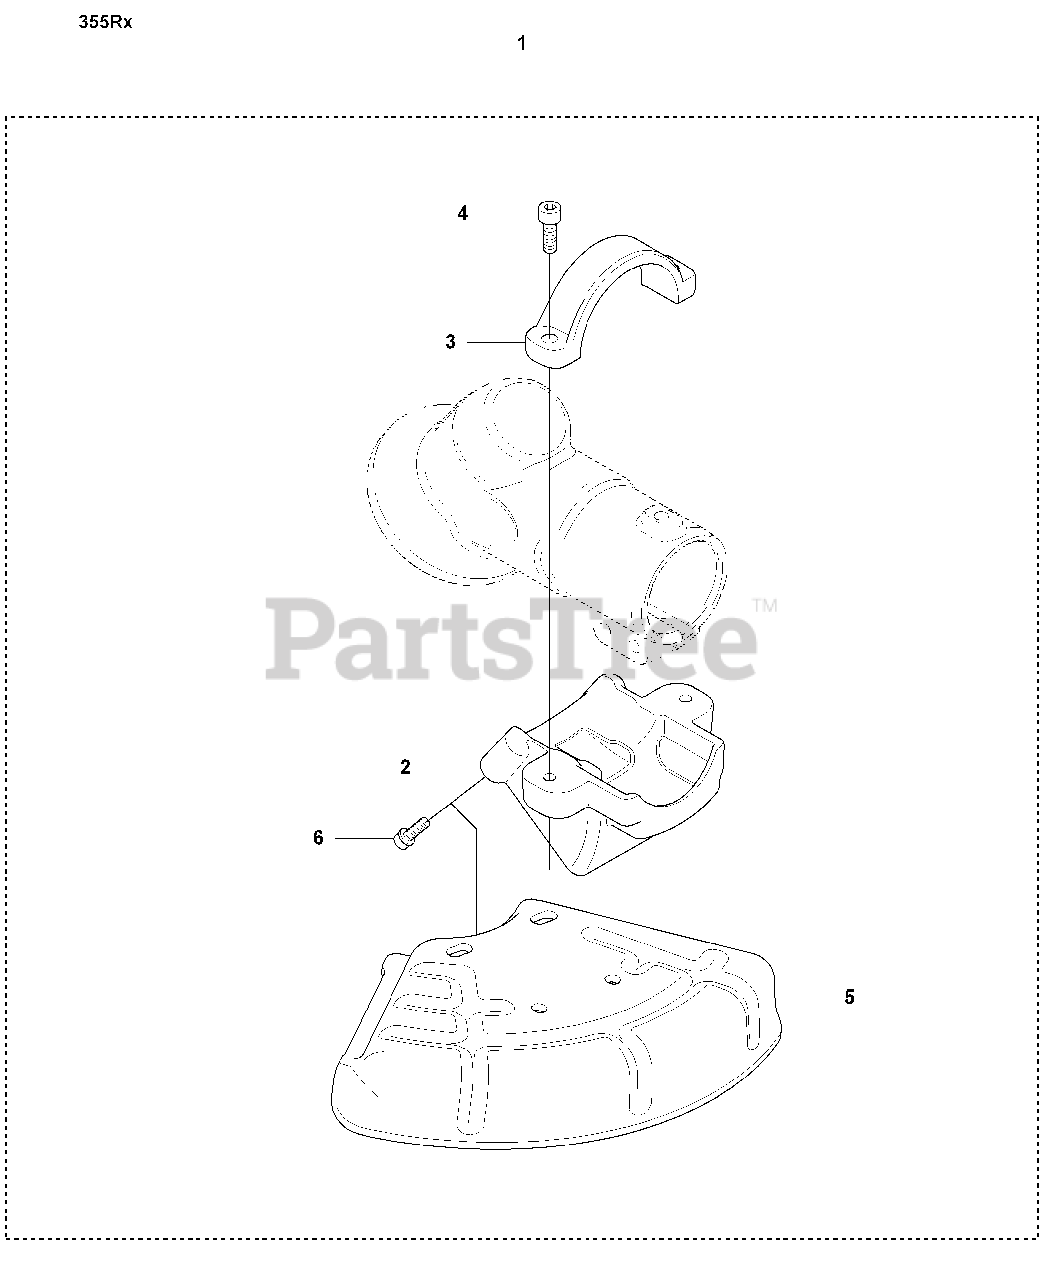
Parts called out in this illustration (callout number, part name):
1	ADAPTER
5	BLADE GUARD SAW
6	SCREW IHSCFM
